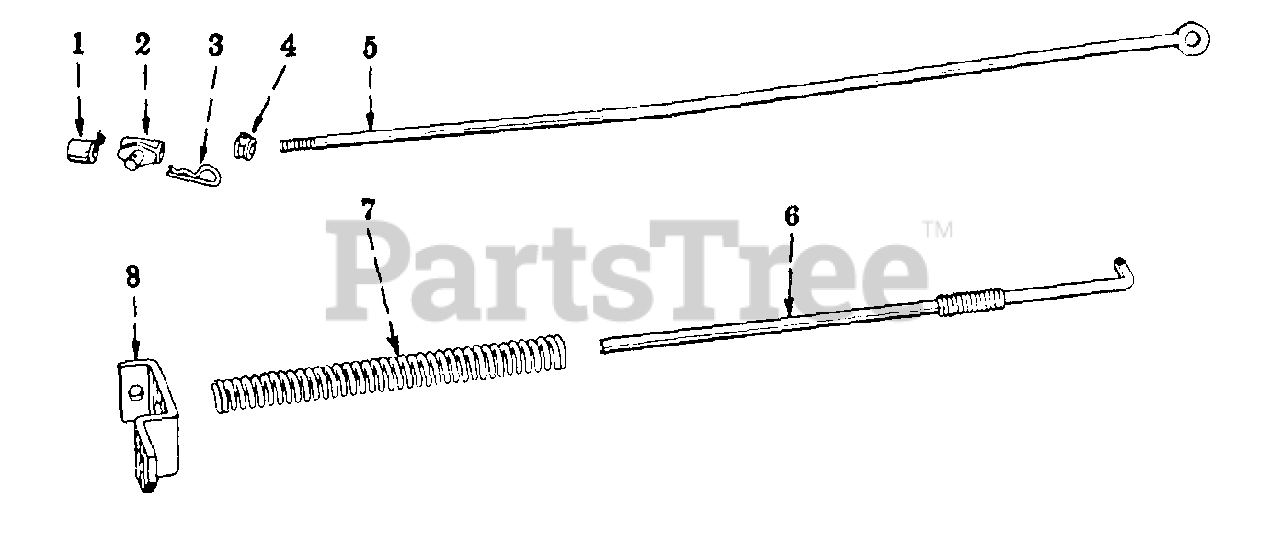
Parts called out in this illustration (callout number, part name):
1	BUSHING, LIFT LINK
2	TRUNNION, LIFT LINK
3	PIN, 3/16 QUICK-ATTACHABLE COT.
4	COLLAR W/SCREW, IH-110448, SET
5	LINK W/NUT, IH-218443, LIFT
6	ROD ASSY, HELPER SPRING
7	SPRING, HELPER
8	GUIDE, HELPER SPRING ROD
